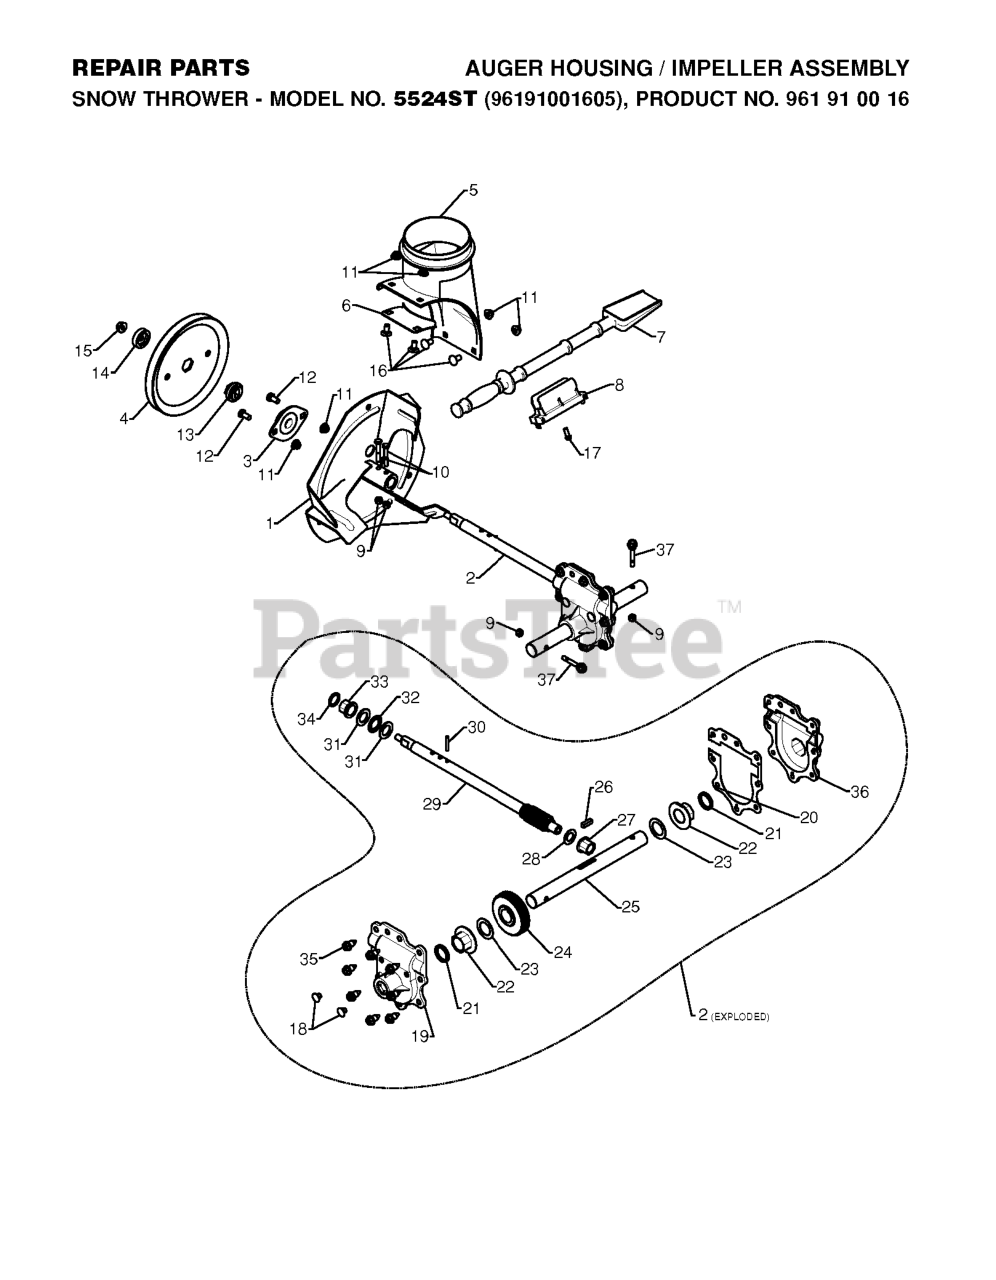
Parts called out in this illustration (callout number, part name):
1	IMPELLER ASSY
2	GEARBOX.ASM.AUGER.D-SHAFT
3	BEARING FLANGE
4	PULLEY.FLANGE.IMPELLER
5	BASE DISCHARGE CHUTE
6	BRACKET, CORNER DISCHARGE
7	CLEAN OUT TOOL
8	CLIP.CLEANOUT.TOOL
9	LOCKNUT.NYLOC.1/4-20
10	SCREW.HEX.HD1/4-20X
11	NUTNYLOK.FLRANGE.5/16-18
12	BOLT, HEX HEAD 5/16-18
13	HUB.IMP.PULLEY.D-SHAFT
14	SLEEVE.IMP.PULLEY.D-SHAFT
15	NUT LOCK FLG 3/8-16 UNC
16	BOLT.CARRIAGE.5/16-18X
17	SCREW.HWH.13-16-5.8.BZP
18	CASE PLUG
19	GEAR.BOX.COVER.RIGHT.SIDE
20	GASKET.GEAR.BOX
21	OIL SEAL
22	FLANGE BUSHING-1"
23	WASHER TRUST 1"
24	WORM GEAR
25	AUGER SHAFT
26	KEY, SQUARE 1/4 X .875
27	FLANGE BUSHING-5/8
28	WASHER, THRUST 5/8
29	SHAFT.IMPELLER.D-SHAFT
30	PIN, ROLL 3/16 X 1-1/8
31	WASHER, THRUST 3/4
32	BEARING TRUST 3/4 NTA-1220
33	BUSHING, FLANGE 3/4
35	HEX SCREW-5/16 X 3/4
36	GEAR.BOX.COVER.LEFT.SIDE
37	BOLT.SHOULDER.SHEAR.1/4-20.
